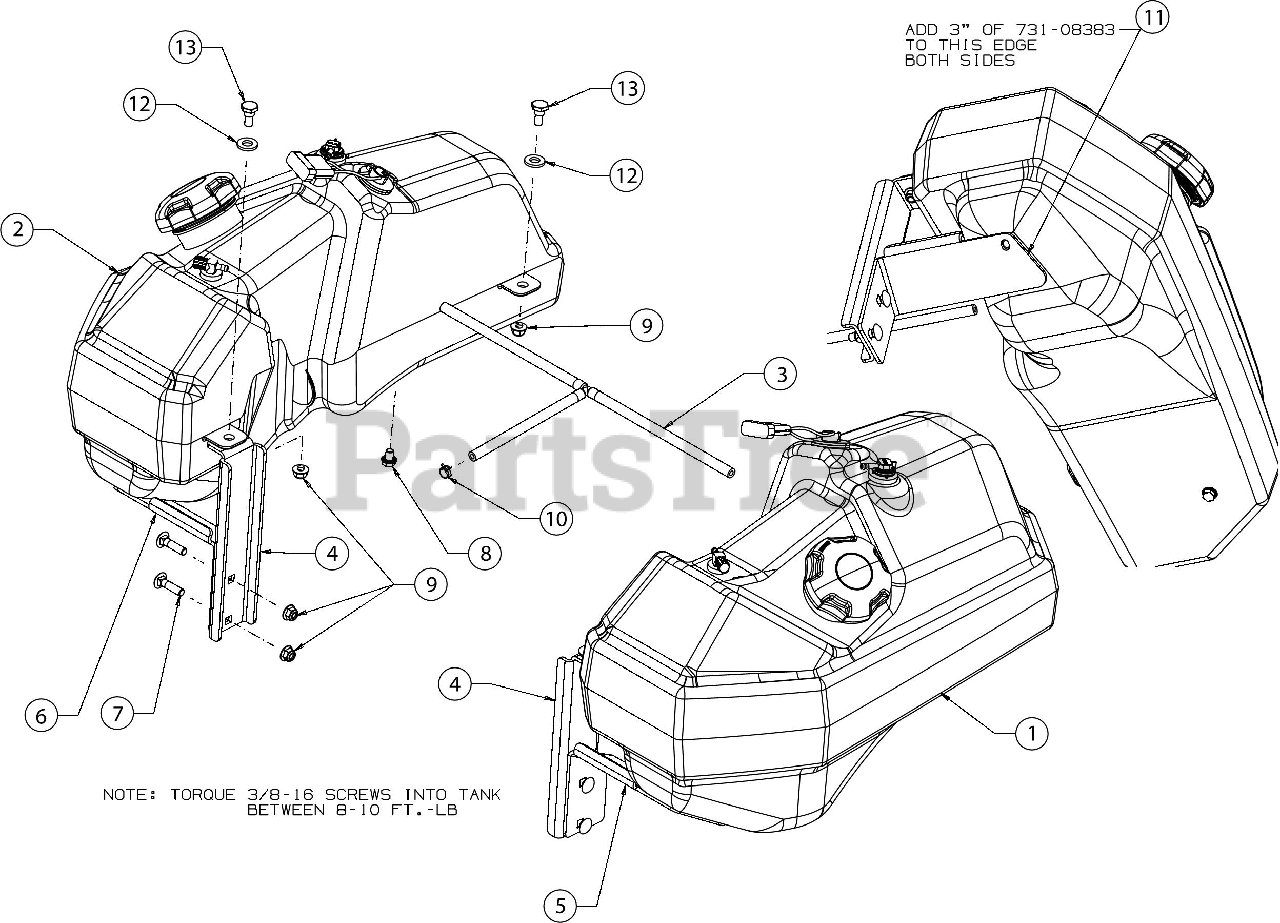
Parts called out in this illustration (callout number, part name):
1	TANK ASSEMBLY (RH) 7.25 GAL
2	TANK ASSEMBLY (LH) 7.25 GAL
3	FUEL HOSE ASSEMBLY
4	FUEL TANK MOUNTING BRACKET
5	FUEL TANK MOUNTING BRACKET (RH)
6	FUEL TANK MOUNTING BRACKET (LH)
7	CARRIAGE BOLT 3/8-16 x 1.50
8	SCREW 3/8-16 x .500 GR5
12	FLAT WASHER .510 x 1.000 x .125
13	SHOULDER SCREW .498 DIA x .340
